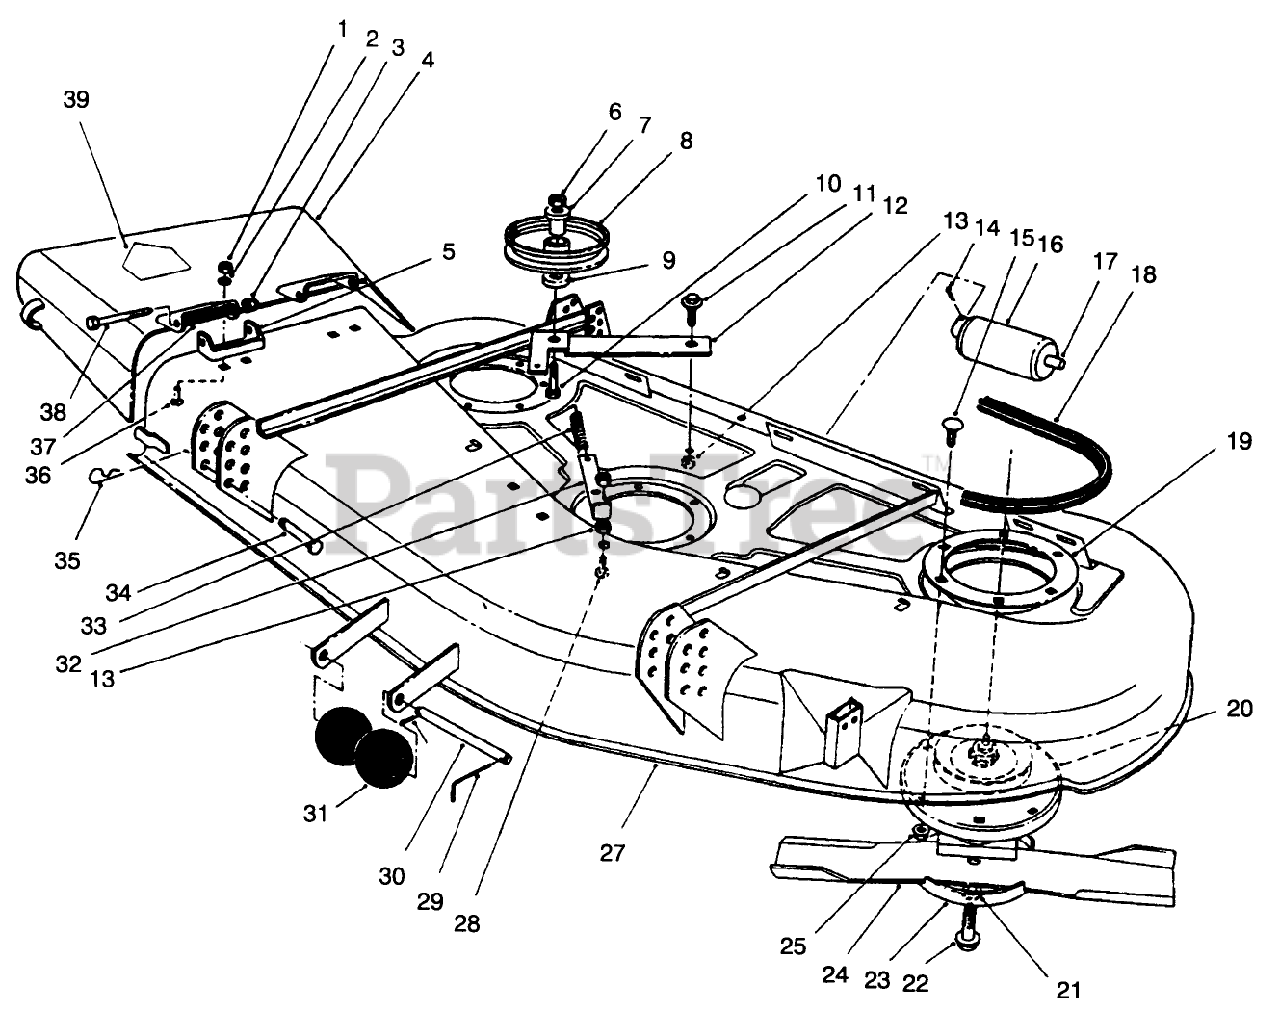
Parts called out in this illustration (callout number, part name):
1	NUT-HEX
2	WASHER-LOCK
3	NUT-HEX
4	Deflector-Grass (Incl. Ref. #39)
5	Bracket-Pivot
6	NUT-HEX
7	BUSHING-PULLEY
8	PULLEY-IDLER
9	WASHER-FLAT
10	SCREW-HH
11	SCREW-SHOULDER
12	Lever-Deck
13	NUT-LOCK, NI
14	PIN-COTTER
15	SCREW-CARR
16	ROLLER-DECK
17	SHAFT-ROLLER, REAR
18	V-BELT, DECK
19	SUPPORT-DECK, RING
20	SPINDLE HSG ASM
21	WASHER-LOCK
22	SCREW-BLADE
23	CUP-SCALP, ANTI
24	Blade
25	NUT-HF
27	Housing (Incl. Ref. #1-2, 29-31, & 40 pg. 2)
28	SCREW-CARR
29	PIN-SPECIAL
30	SHAFT-ROLLER
31	ROLLER
32	Anchor-Spring
33	SPRING-EXTENSION, DECK
34	PIN-CLEVIS
35	PIN-HAIR
36	SCREW-CARR
37	SPRING
38	SCREW-HH
39	DECAL-DANGER
